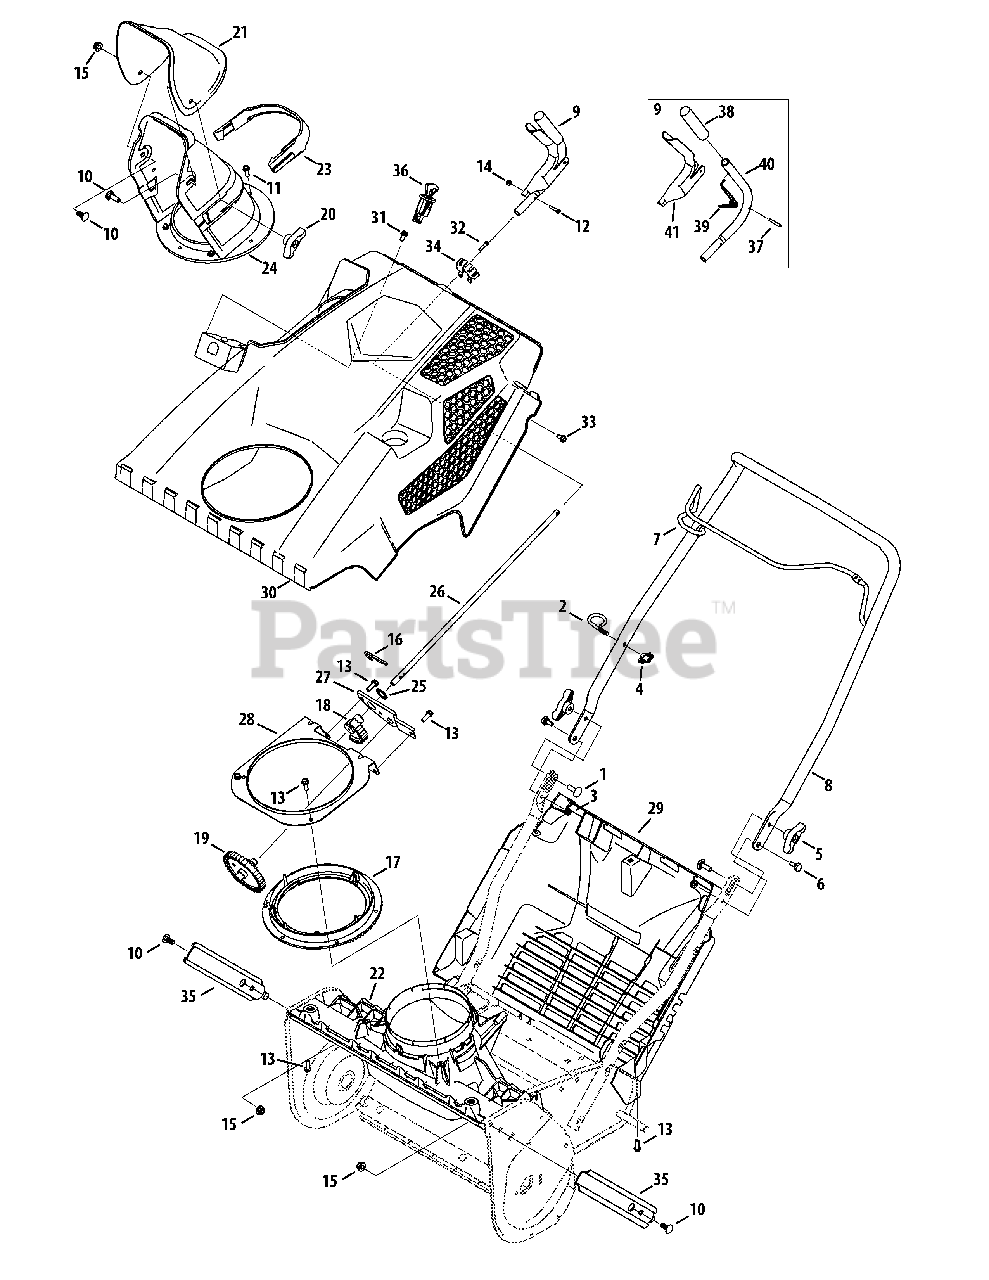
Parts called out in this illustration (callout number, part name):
1	Carriage Bolt, 5/16-18 x 1.00
2	Eye Bolt, 1/4-20
3	Flange Lock Nut, 1/4-20
4	Knob Handle
6	Shoulder Screw, .375 x .148 x 1/4-20
8	Upper Handle
9	Chute Control Assembly
10	Carriage Bolt, 5/16-18 x .75
11	Hex Washer Screw, 1/4 x .750
12	Screw, #8-32 x .875
13	Screw, Hi-Lo:1/4-15, 0.75
14	Hex Lock Nut, #8-32
15	Flange Lock Nut, 5/16-18
16	Cotter Pin
17	Bevel Gear, 95T
18	Spur Gear, 35T
19	Bevel Gear, 40T/11T
20	Wing Knob, 5/16-18
21	Upper Chute
22	Chute Adapter
23	Chute Plug
24	Lower Chute
25	Flat Washer, .75 x 1.00 x .06
27	Gear Mounting Plate
28	Gear Retainer Bracket
29	Bottom Cover
30	Top Cover
31	Hex Washer Screw, 1/4-15 x .50
32	Hex Washer Screw, #8-16 x .50
33	Hex Washer Screw, 1/4-20 x .625
34	Index Bracket
36	Ignition Switch Assembly
39	Torsion Spring
40	Chute Rotation Tube
41	Chute Rotation Bracket
